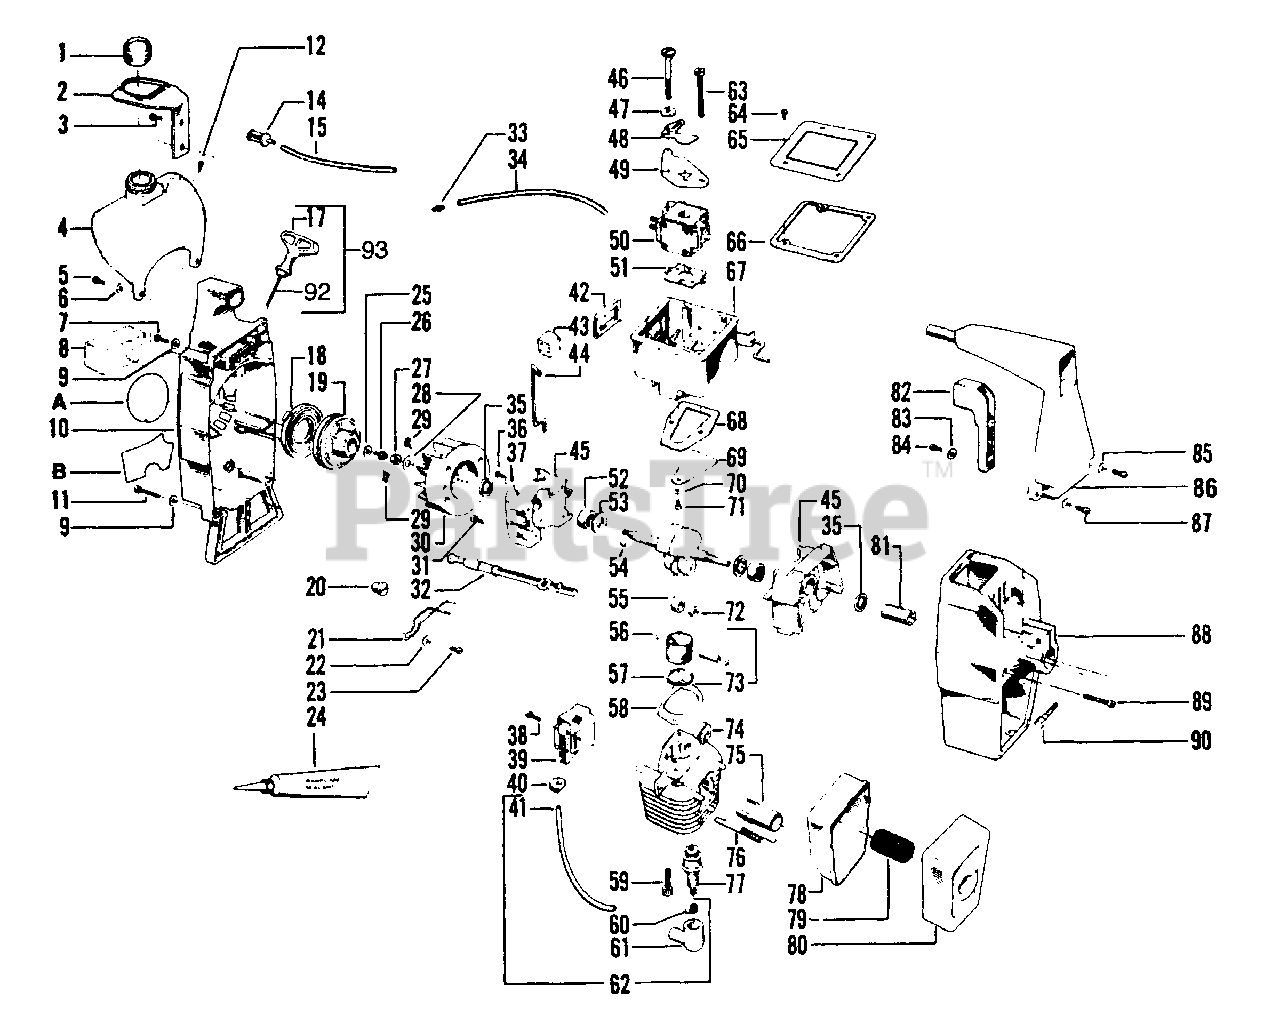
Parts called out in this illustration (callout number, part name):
1	Fuel Cap Assembly (AYP part number)
2	Bracket - Fuel Tank
3	Screw -Bracket/Handle (1/4 - 10 x 1-1/8)
4	Fuel Tank Assembly
5	Screw- Fuel Tank/Fan Housing (10-1)
6	Washer - Fuel Tank/Fan Housing
7	Screw -Fan Hsg. Top #10 - 24 x 5/8 Fit.
8	Air Filter
9	Washer - Flat - Fan Housing
10	Fan Housing
11	Screw -Fan Housing - Bottom - #10 - 24 x 1-3/16 Fil.
12	Check Valve - Duck Bill
14	Fuel Pick-Up Ass'y.
15	Line - Fuel Pick-up
17	Handle - Starter
18	Starter - Recoil Spring
19	Starter - Pulley
20	Button - Kill Switch
21	Spring - Kill Switch
22	Washer - Kill Switch
23	Screw- Kill Switch (8 x 3/8)
24	Crankcase Sealant - 3 oz. tube
25	Washer - Starter Pulley
26	Screw - Starter Pulley (# 10 - 3/4 - Hex Head)
27	Nut - Flywheel
28	Spring - Starter Dog
29	Washer - Flywheel
30	Flywheel Ass'y
31	Screw - Crankcase (# 10 - 24 x 5/8 Fil.)
32	Knob-Choke
33	Fitting - Fuel Line
34	Fuel Line - Carburetor
35	Seal - Crankshaft
36	Screw - Clamp # 8 - 32 x 5/16 Pan.
37	Clamp - Choke Wire
38	Screw -Ignition Module (8 - 32 x 3/4 - Sems)
39	Ignition Module
40	Grommet - Plug Wire
41	Lead Wire - High Tension
42	Seat - Carburetor Case
43	Boot - Choke Wire
44	Wire - Choke
45	Crankcase Ass'y
46	Screw - Carburetor (Shoulder # 10 - 24)
47	Wave Washer
48	Shutter - Choke
49	Plate - Guide, Choke Wire
50	Carburetor
51	Gasket Carburetor
52	Bearing - Crankshaft
53	Thrust Washer - Crankshaft
54	Key - Flywheel
55	Crankshaft & Rod Assembly
56	Retainer - Wrist Pin
57	Piston Ring
58	Gasket Cylinder
59	Screw - Cylinder (1/4 - 20 x 3/4 Socket Head)
60	Connector - Spark Plug
61	Boot - Spark Plug
62	High Tension Lead Ass'y
63	Screw-Carburetor (# 10 - 24 Fil.)
64	Screw Carburetor Cover (8 - 18 x 9/16)
65	Cover Carburetor Case
66	Gasket - Carburetor Case Cover
67	Carburetor Case Assembly
68	Gasket Carburetor Case/Crankcase
69	Reed Valve
70	Washer - Reed Valve
71	Screw - Reed Valve (6 - 19 x 5/16)
72	Bearing - Wrist Pin
73	Piston Ass'y
74	Cylinder
75	Diffuser Muffler
76	Spring - Muffler Attachment
77	Spark Plug (RCJ-8)
78	Body Muffler
79	Screen-Spark Arrestor
80	Cover-Muffler
81	Coupling - Hex Drive
82	Trigger - Throttle
83	Washer - Throttle
84	Screw - Throttle (8 - 16 x 3/8)
85	Washer - Flat - Shroud
86	Handle
87	Screw - Shroud (Top) - (10 - 24 x 7/8)
88	Shroud
89	Screw - Shroud (Bottom) - # 10 - 24 x 1-1/2 Fil.
90	Bolt, Pinch Clamp (1/4 - 20 x 1 - Hex Cap)
92	Rope (3 1/2 Ft.)
93	Rope & Handle - Starter Ass'y
A	Decal - Starting instructions
B	Decal - Choke / OFF
